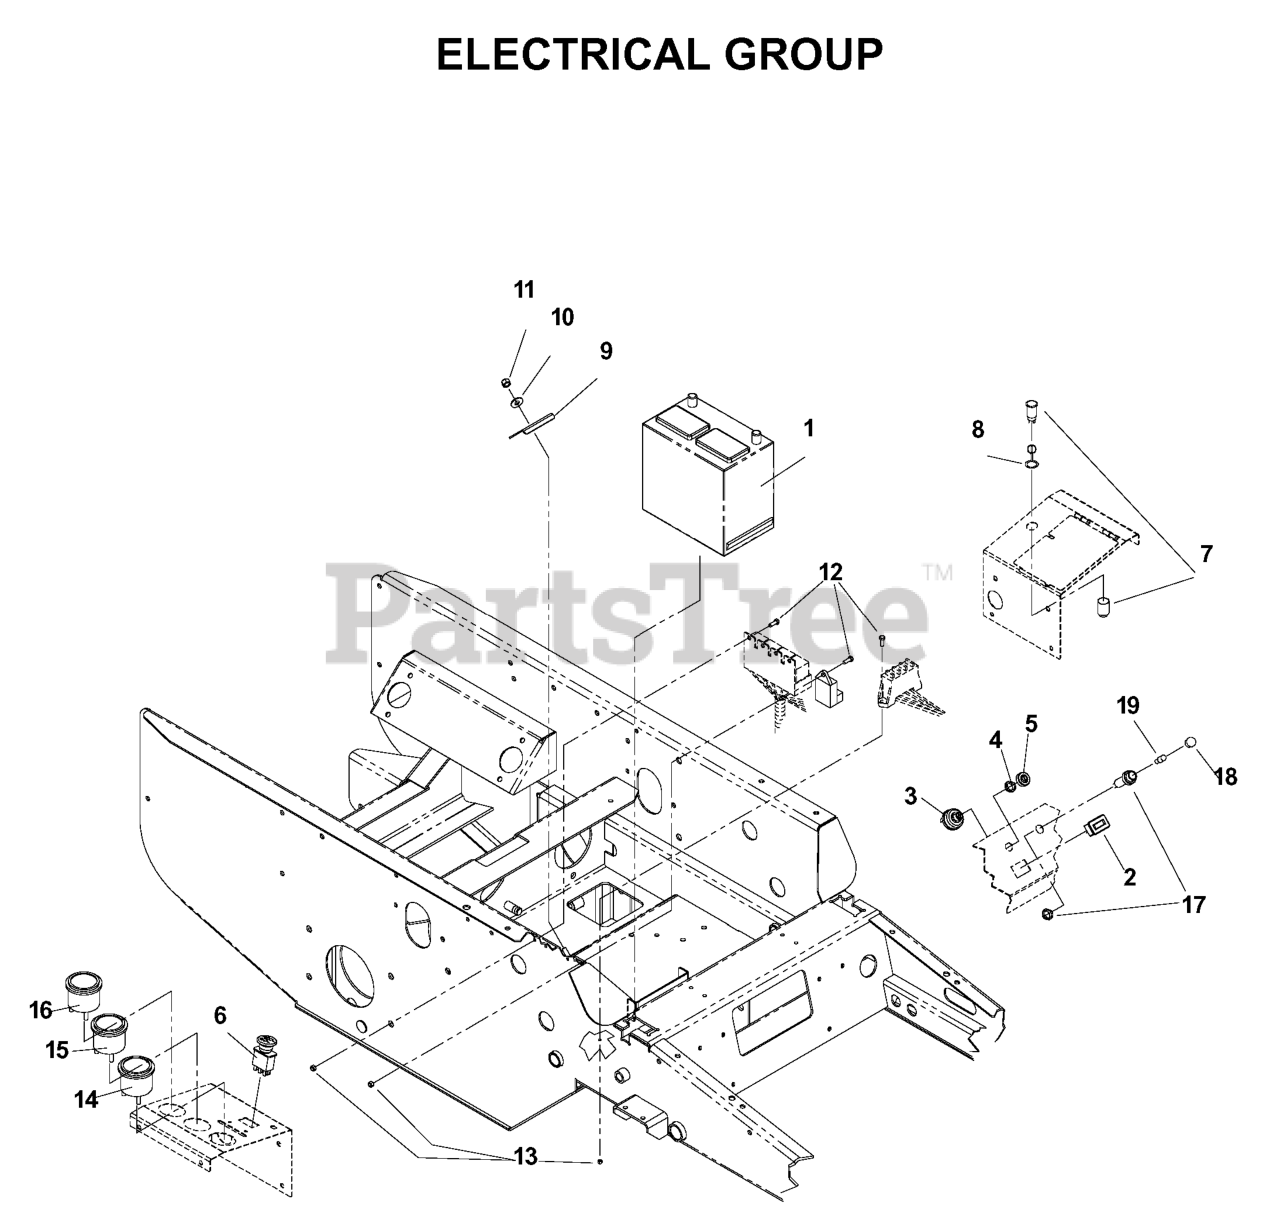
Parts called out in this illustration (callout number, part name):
2	DIGITAL HOUR METER
3	IGNITION SWITCH KIT
4	DNO IGNITION NUT
5	CAP IGNITION NUT
6	RP.SWITCH, BLADE
7	POWER SOURCING HSG
8	POWER SOURCE CAP
10	WASHER 5/16 FLAT
11	NUT 5/16 NYLOC
12	SCREW 10-24 X 3/4
13	NUT 10-24 NYLOC
14	TEMP GAUGE DATCON #100182
15	GAUGE, AMPMETER DATCON 100160
16	GAUGE, OIL PRES DATCON 100172
17	LAMP SPROCKET
539108348	TIMER/GLOW PLUG
